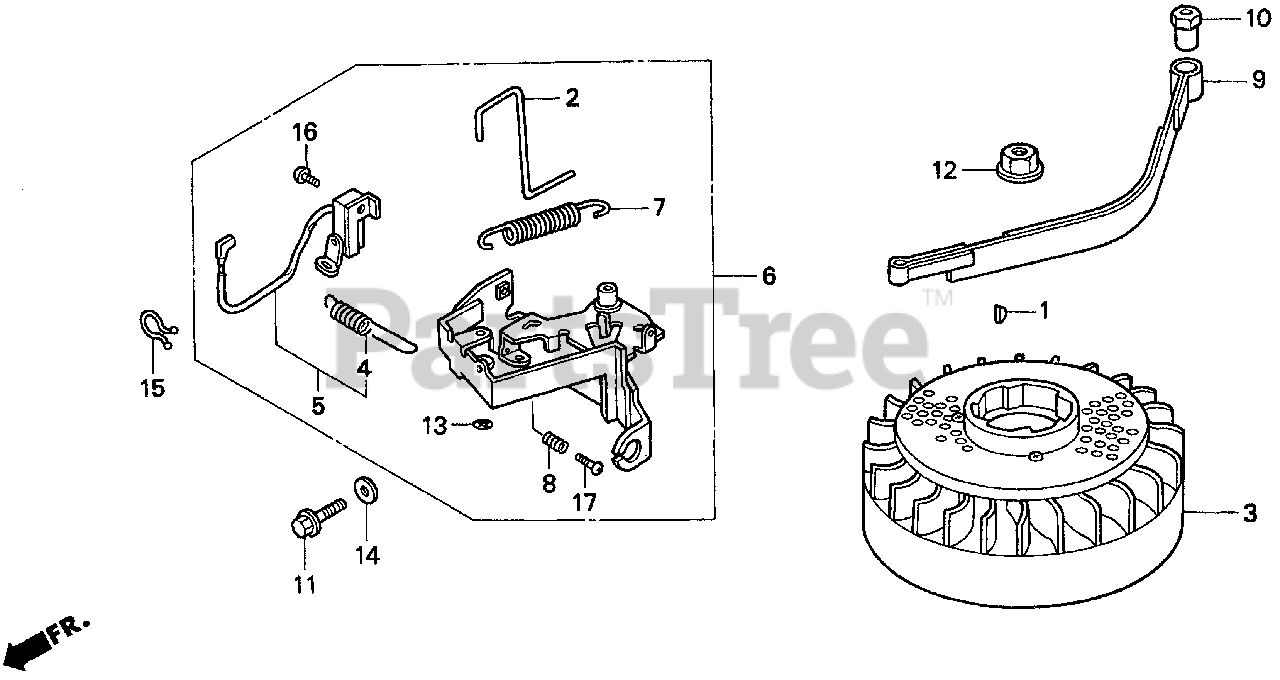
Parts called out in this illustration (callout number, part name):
1	KEY, SPECIAL WOODRUFF (25X18)
2	ROD, GOVERNOR ARM RETURN
3	FLYWHEEL ASSY.
4	SPRING, SWITCH CONTROL
5	SWITCH ASSY., ENGINE STOP
6	LEVER ASSY., BRAKE
7	SPRING, BRAKE LEVER
8	SPRING, BRAKE ADJUSTING
9	BRAKE
10	COLLAR, BRAKE SHAFT
11	BOLT, FLANGE (6X14)
12	NUT, SPECIAL (14MM)
13	NUT, PUSH (2.6)
14	WASHER, SEALING (6.5X12)
15	CLIP, PURSE LOCK
16	SCREW, PAN (4X8)
17	SCREW, PAN (5X12)
